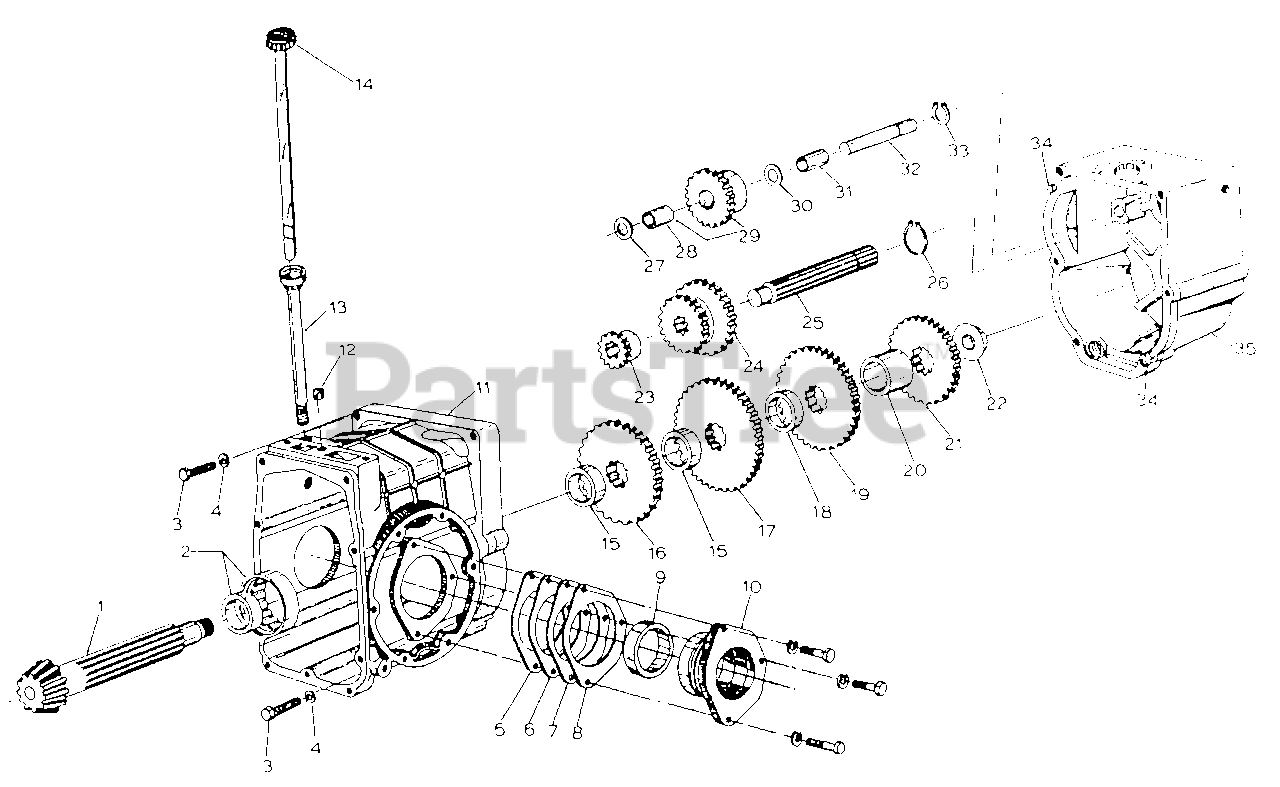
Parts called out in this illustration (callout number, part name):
1	Shaft, Pinion -10T
2	Bearing Assy, Roller
3	Bolt, 7/16 X 1-3/4 Type 5
4	Washer, 7/16 ID Belleville
5	Shim, Bearing Retainer, .004
6	Shim, Bearing Retainer, .007
7	Shim, Bearing Retainer, .014
8	Shim, Bearing Retainer
9	Bearing, Differential Cup
10	Retainer, Differential Bearing
11	Housing Assy, Rear w/Main Shaft Needle Bearing
12	Plug, Breather
13	Tube, Dipstick
15	Spacer, First and Reverse Speed Gear and Countershaft Brg
16	Gear, Reverse Speed -35T
17	Gear, First Speed -39T
18	Spacer, First & Second Speed Gear
19	Gear, Second Speed -35T
20	Spacer, Second and Third Speed
21	Gear, Third Speed -26T
22	Spacer, Third Speed Gear and Countershaft Bearing
23	Gear, First & Reverse Speed Sliding -13T
24	Gear, Second & Third Speed Sliding -17T & -26T
25	Shaft, Main
26	Ring, .867 Ext Ret
29	Gear, Reverse Idle w/Bushing -22T
30	Washer
32	Shaft, Reverse Idle
33	Ring, .543 Hvy Ext Ret
34	Pin, Dowel
35	Housing Gear
